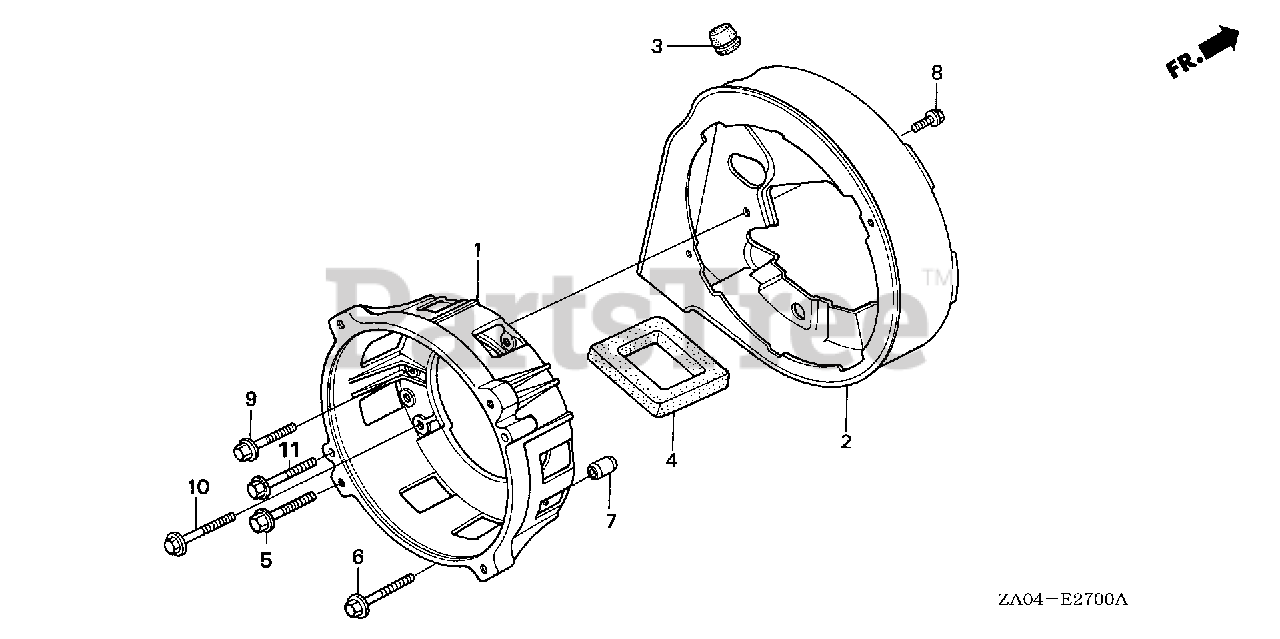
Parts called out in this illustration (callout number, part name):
1	HOUSING, FR.
2	COVER, DUCT
3	GROMMET, DUCT COVER
5	BOLT, FLANGE (8X32)
6	BOLT, FLANGE (8X40)
7	PIN A, DOWEL (10X14)
8	BOLT, FLANGE (6X12) Use up to Engine SN 1543277.
9	BOLT, FLANGE (8X32)
10	BOLT, FLANGE (8X40) Use up to Engine SN 1003236.
11	BOLT, FLANGE (6X40)
